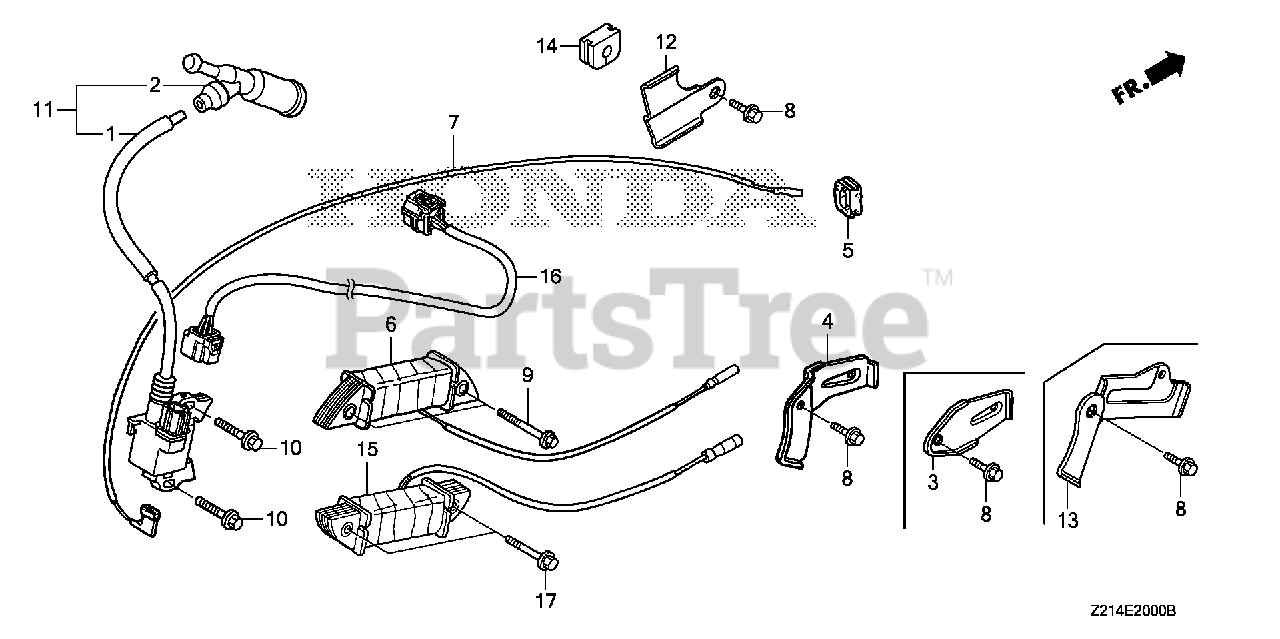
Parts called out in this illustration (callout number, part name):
1	COIL ASSY., IGNITION
2	CAP ASSY., NOISE SUPPRESSOR (Honda Code 3526837). (NICHIWA Y-EZ RTFM256)
2	CAP ASSY., NOISE SUPPRESSOR (NGK Y-EZDB)
4	CLAMP, WIRE
5	GROMMET, WIRE
6	COIL ASSY., CHARGE (1A)
7	WIRE, STOP SWITCH (470MM)
8	BOLT, FLANGE (6X12) (CT200)
9	BOLT, FLANGE (6X35)
10	BOLT, FLANGE (6X28) (CT200) Use up to Engine SN 1530314.
